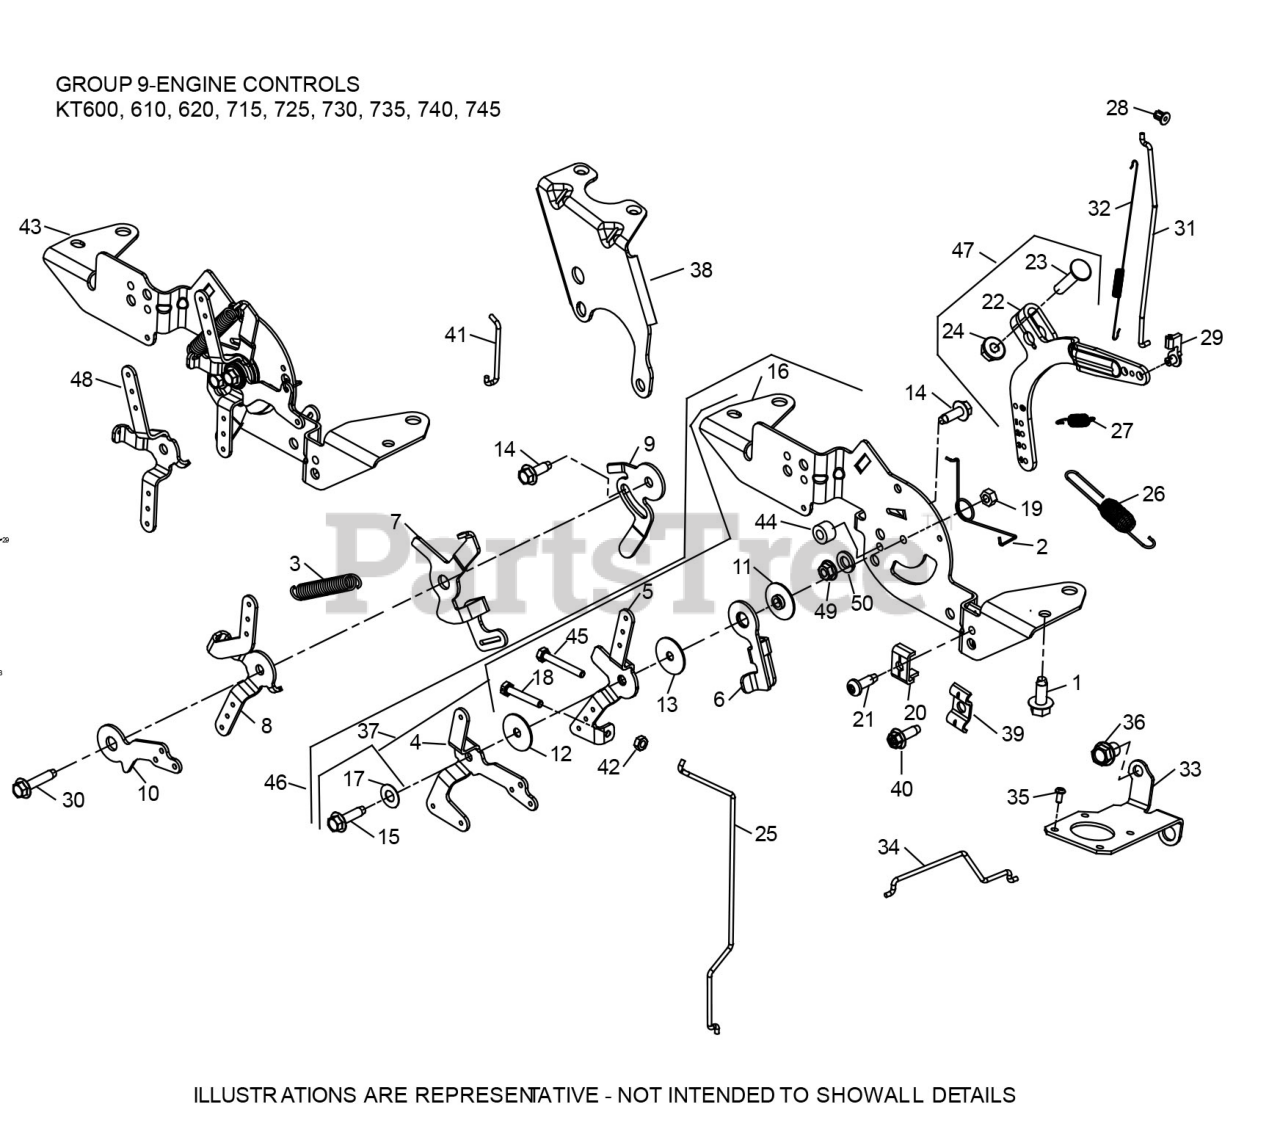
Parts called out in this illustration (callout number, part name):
1	SCREW-THREAD FORMI
2	SPRING-CHOKE RETRN
5	LEVER-THROTTLE CON
6	LEVER-THROTTLE ACT
11	SPACER-CONTROL ASSEMBLY
15	THREAD FORMING SCREW
16	SPEED CONTROL BRACKET
22	LEVER-GOVERNOR ASSEMBLY
23	BOLT-RD HD SQ NECK
24	HEX FLANGE NUT
25	CHOKE LINKAGE
26	GOVERNOR SPRING
27	GOVERNOR SPRING
29	BUSHING-RETAINING
32	LINKAGE SPRING
34	THROTTLE LINKAGE
40	THREAD FORMING SCREW
46	SPEED CONTROL ASSEMBLY
47	LEVER-GOVERNOR ASSEMBLY
